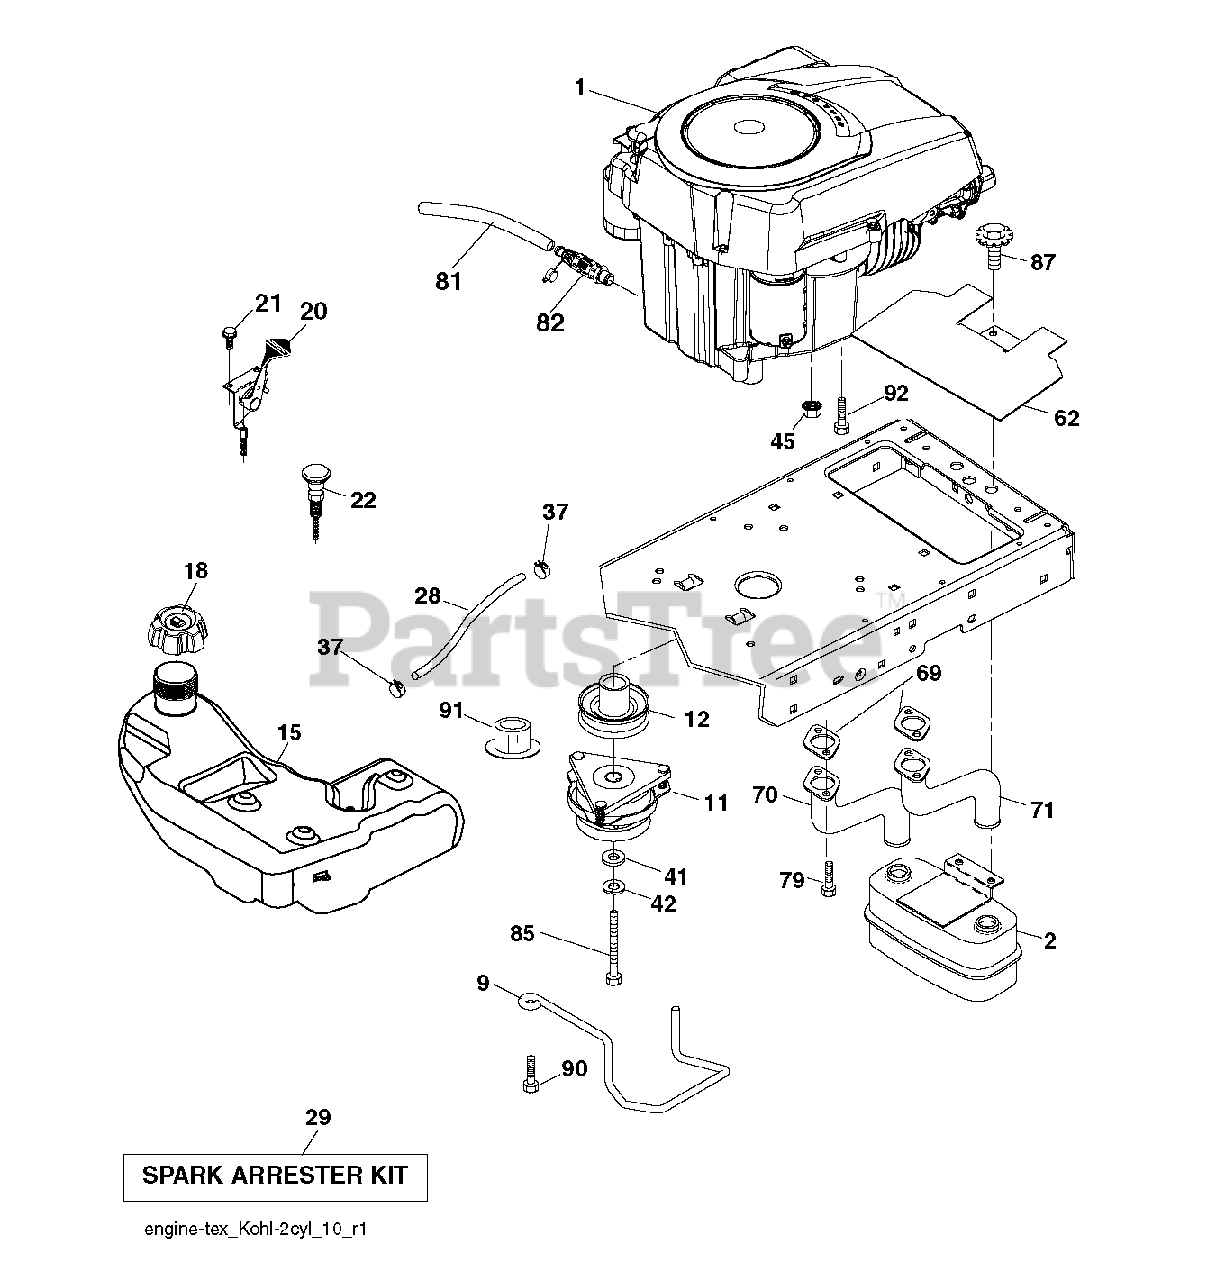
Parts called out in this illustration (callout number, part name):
2	MUFFLER.ASM.TWN.EXTNDED.DFLCTR
9	KEEPER.BELT.ENGINE.4.2
11	CLUTCH.ELECTRIC.LT.48"*
12	PULLEY.ENGINE.TUFFTORQ
15	TANK.FUEL.SIDE-FILL.3.NON-EPA
18	CAP.FL.R.3'N/CARB.H.CROWN.498
20	THROTTLE CONTROL
21	SCREW.#10 X 0.750.BOS
22	CONTROL.CHOKE.ERGO.PUSH-IN.BLA
28	LINE.FUEL.64"REAR.EMIS
29	KIT.SPARK ARRESTOR 794945 B&S
37	HOSE CLAMP
42	LOCKWASHER
45	NUT
62	RP SHIELD HEAT MUFFLER
69	GASKET.EXHAUST.KOHL.CV18-CV26
70	RP.PIPE-EXHAUST LH
71	RP.PIPE-EXHAUST RH
79	SCREW.SOCKET HD.5/16-1
81	TUBE, DRAIN OIL ASM.
82	VALUE.OIL.DRAIN
85	BOLT HEX 7/16-20X4-1/4"
87	BOLT, 5/16-18 X 1 3/4
90	SCREW 3/8-16X1
91	BUSHING.1.375OD
92	SCREW 3/8-16X1
